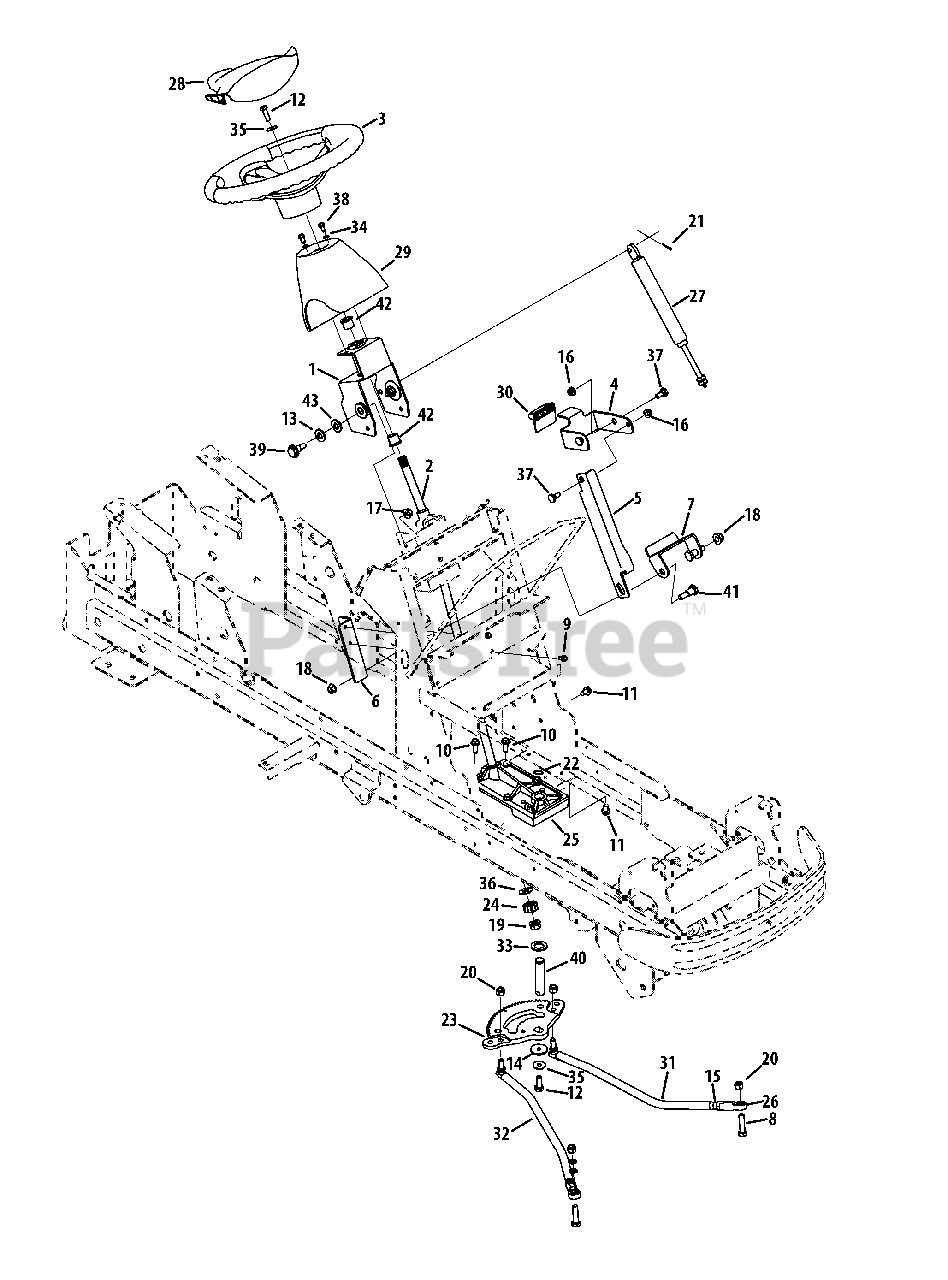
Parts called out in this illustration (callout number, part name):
1	Steering Upper Support Bracket
2	Manual Steering Assembly
3	Steering Wheel
4	Tilt Steering Lever Bracket
5	Tilt Steering Bracket
6	Tilt Steering Mount Bracket
7	Tilt Steering Pivot Bracket
8	Hex Screw, 3/8-24 x 2.00
9	Hex Washer Screw, 1/4-20 x .500
10	Hex Washer Screw, 5/16-18 x 1.000
11	Hex Washer Screw, 5/16-18 x .625
12	Hex Lock Screw, 5/16-18 x 1.00
13	Flat Washer, .510 x 1.14 x .040
14	Flat Washer, .340 x 1.50 x .150
15	Jam Nut, 7/16-20
16	Flange Lock Nut, 5/16-18
17	Flange Lock Nut, 3/8-16
18	Flange Lock Nut, 3/8-16
19	Flange Lock Nut, 7/16-20
20	Hex Lock Nut, 3/8-24
21	Cotter Pin, 3/32 x .750
22	Snap Ring, .750
23	Segment Gear
24	Pinion Gear
25	Steering Housing
26	End Rod, 7/16-20 x 3/8
27	Locking Damper Cylinder
28	Steering Wheel Cover
29	Dash Collar
30	Tilt Lever
31	LH Drag Link, 5/8
32	RH Drag Link, 5/8
33	Flat Washer, .76 x 1.25 x .10
34	Flat Washer, .344 x .62 x .033
35	Bell Washer, .340 x .872 x .060
36	Thrust Washer, .510 x 1.12 x .060
37	Shoulder Screw, .435 x .178-5/16 x .56
38	Shoulder Screw, 1/4-20 x 0.500
39	Shoulder Bolt, 3/8-16 x .49 x .33
40	Steering Shaft
41	Shoulder Screw, 3/8-16 x .50 x .66
42	Flange Bearing, .630
43	Flat Washer, .580 x 1.125 x .080
